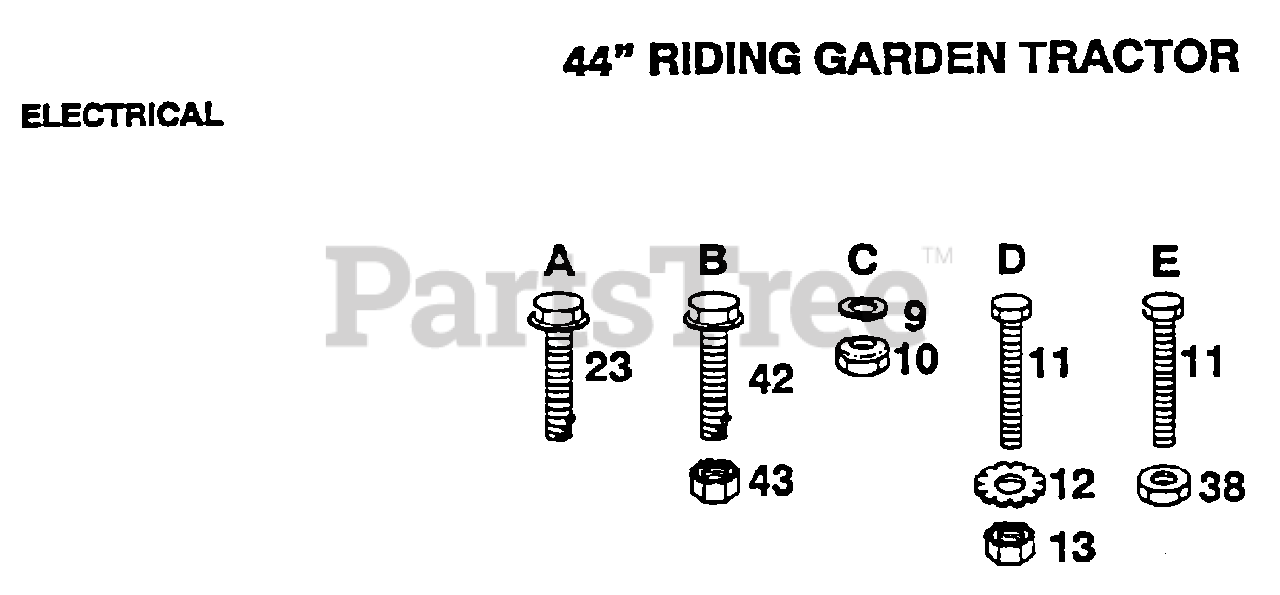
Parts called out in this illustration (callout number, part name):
10	NUT
11	BOLT
13	NUT
23	SCREW
42	SCREW
43	"NUT,KEPS"
